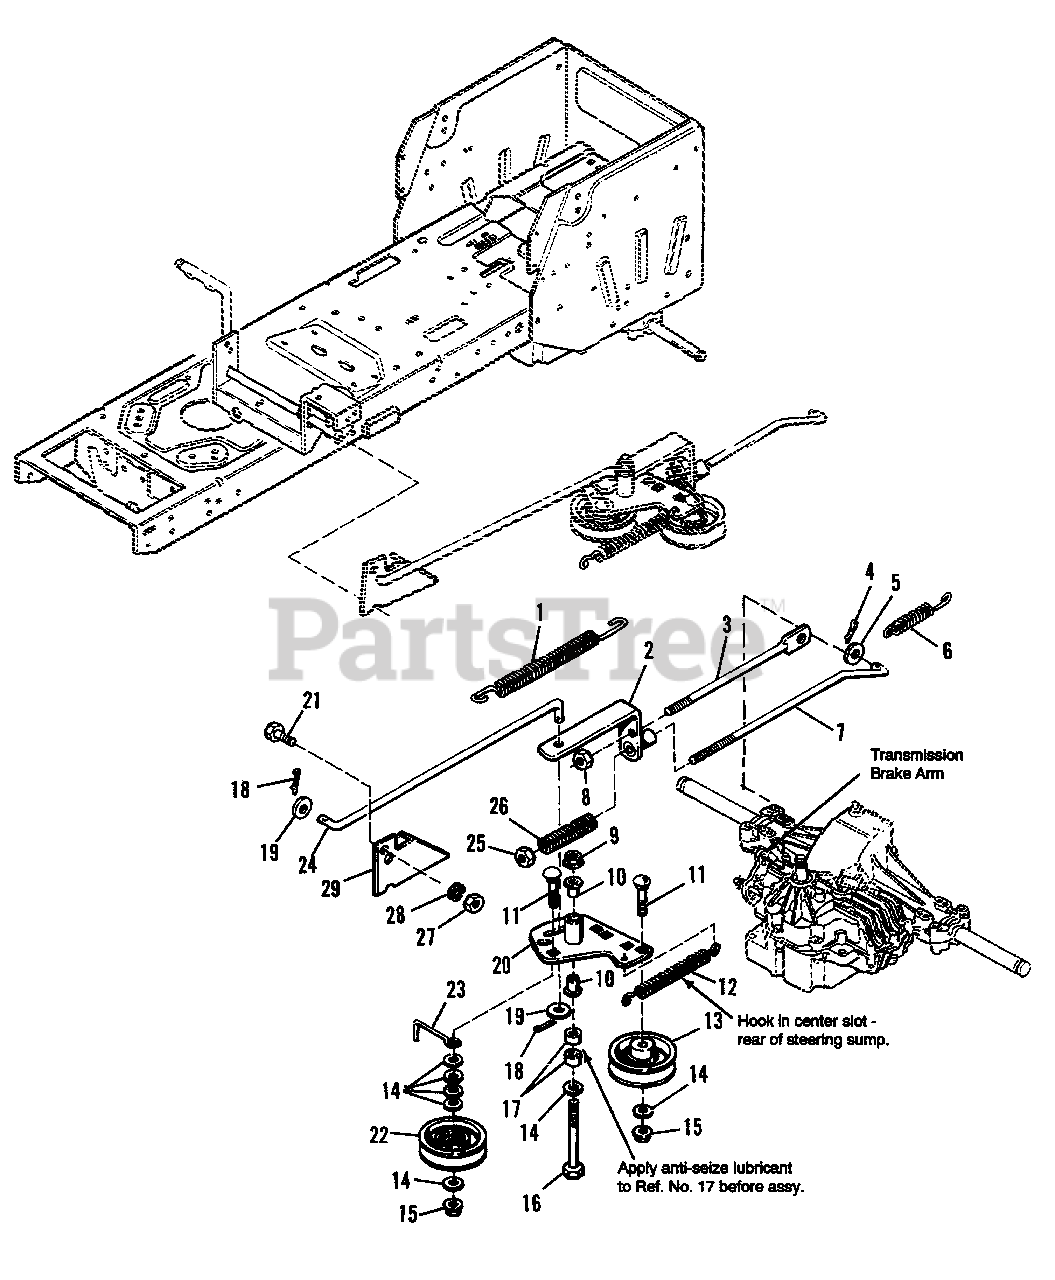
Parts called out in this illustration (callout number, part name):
1	SPRING, External
2	BRAKE ARM ASSY.
3	ROD, Return
4	COTTER PIN, 3/32 x 3/4
5	WASHER, Plain, 11/32 x 3/4 x 1/16
6	SPRING, External
8	NUT, Hex, Esna, Lock, 3/8-16
9	NUT, Flange, Whizlock, 3/8-16
10	BUSHING, Plastic
11	CARRIAGE BOLT, 3/8-16 x 1-3/4
13	PULLEY, Idler
14	WASHER, 13/32 x 7/8 X 5/64
15	NUT, Flange, Whizlock, 3/8-16
16	CAPSCREW, Hex Hd., 3/8-16 x 3
18	COTTER PIN, 3/32 x 3/4
19	WASHER, Plain, 11/32 x 3/4 x 1/16
20	IDLER ARM ASSY.
21	CAPSCREW, Hex Hd., 5/16-18 x 3/4
22	PULLEY, "V"
24	ROD, Clutch
25	NUT, Hex, Esna, Lock, 3/8-16
27	NUT, Hex, 3/8-16
28	LOCKWASHER, Spring, 3/8
29	ACTUATOR, Switch
